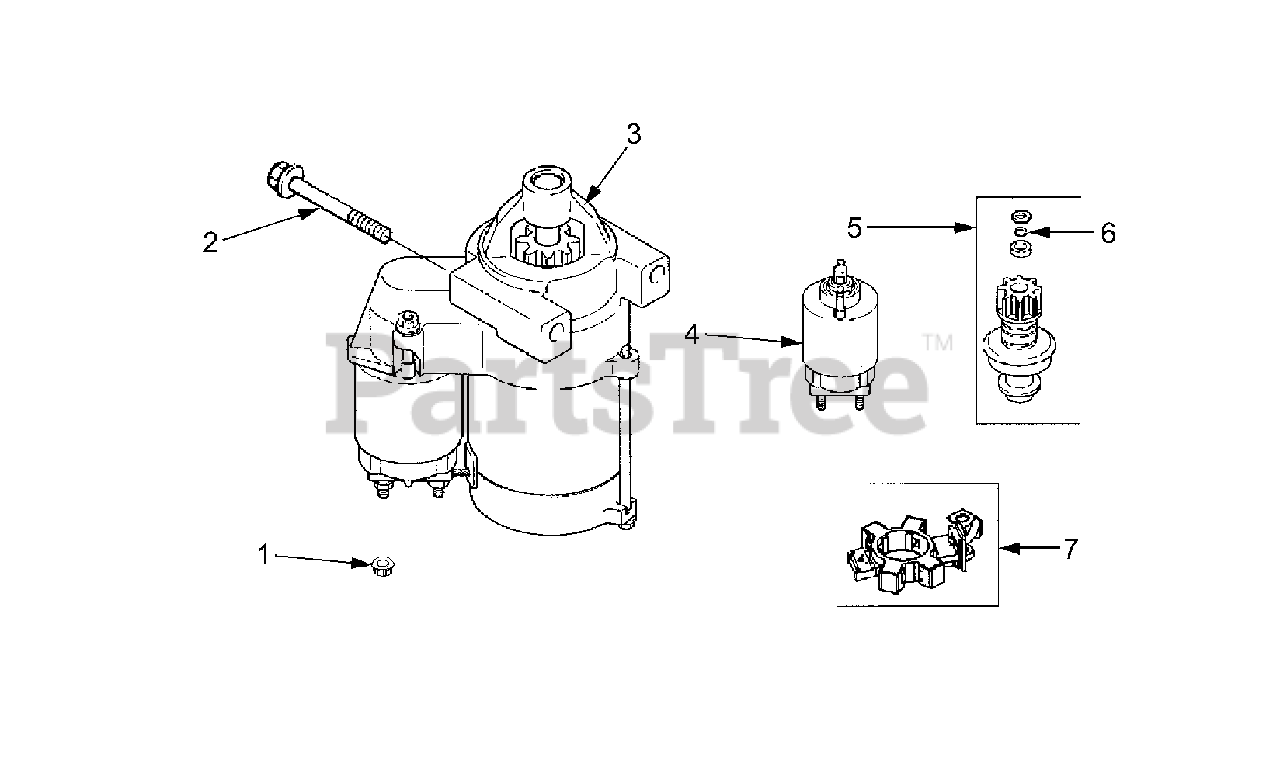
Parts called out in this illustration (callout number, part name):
1	Nut, Hex Flange M8 x 1.25"
2	Screw, Hex Flange M8 x 1.25 x 80
3	Starter assembly, solenoid shift (Delco)
4	Kit, Solenoid
5	Kit, Pinion Drive
6	Ring, Retainer
